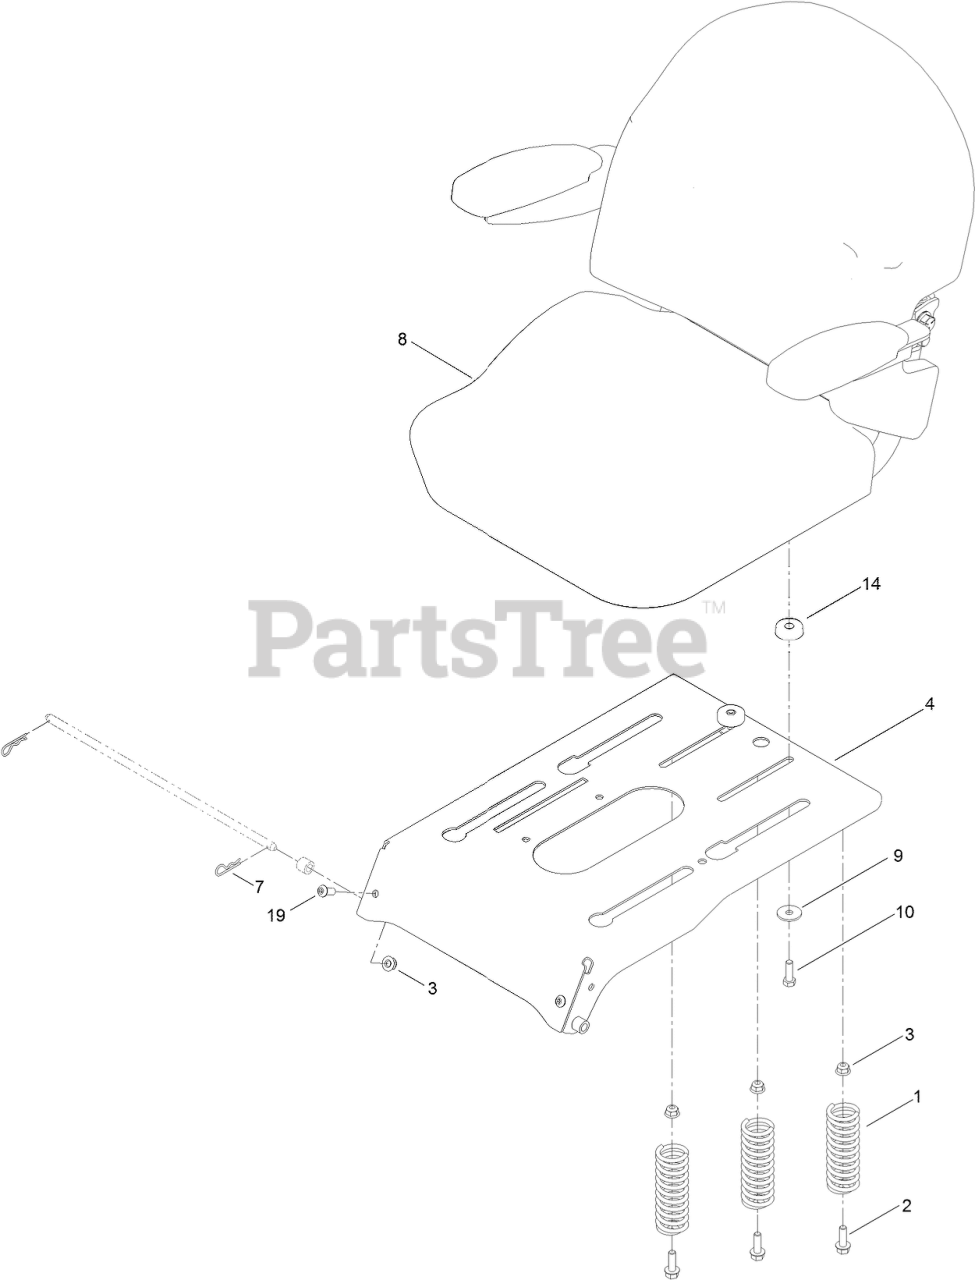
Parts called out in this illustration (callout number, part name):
1	SPRING-COMPRESSION
2	SCREW-HHF
3	NUT-HF, NI
4	PAN-SEAT, DELUXE
7	PIN-COTTER
8	SEAT ASM
9	WASHER-PIVOT
10	SCREW-HH
14	BUSHING-SLIDE, SEAT
19	SCREW-HSBH
